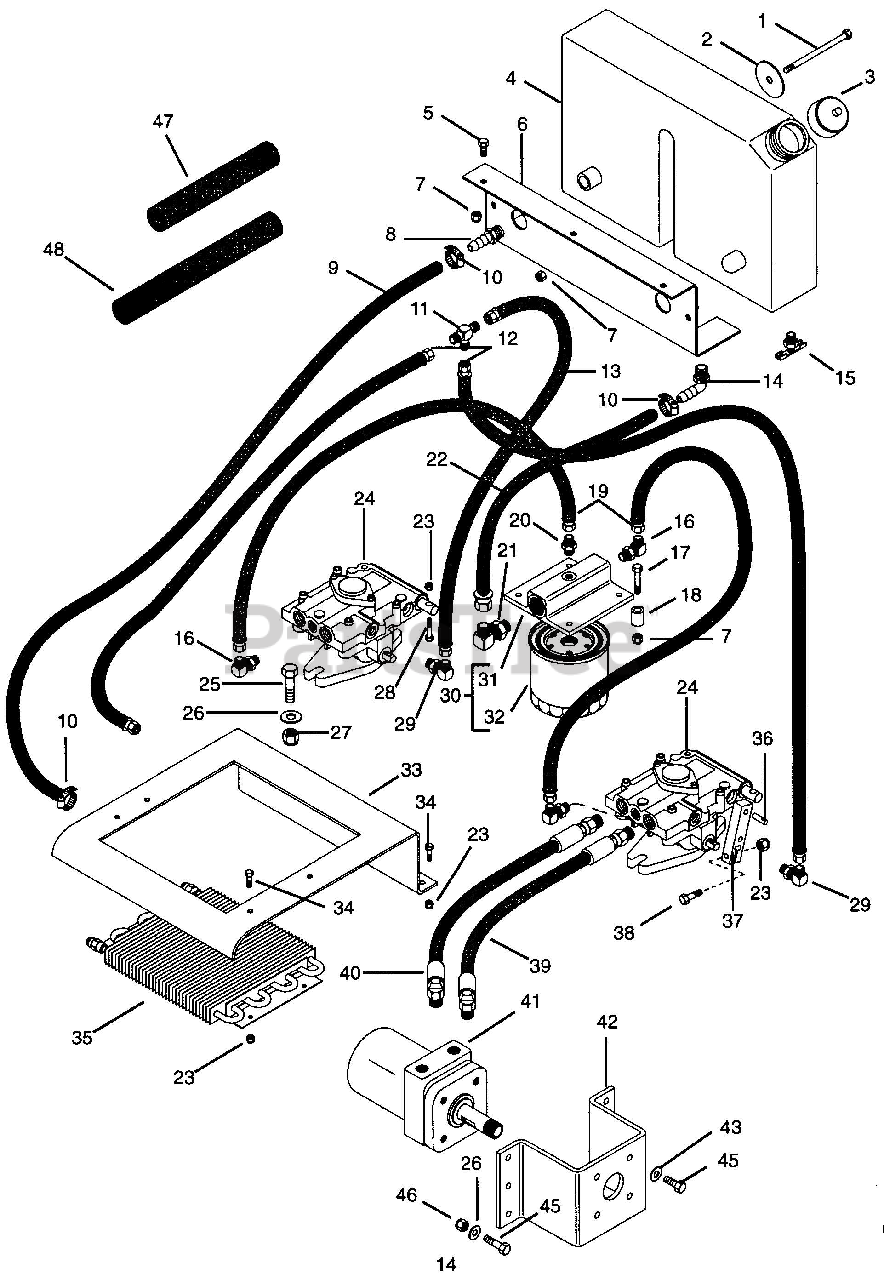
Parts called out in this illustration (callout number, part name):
1	Bolt-Hex .31-18 x 3.50
2	Washer-Flat .344 x 3.0 x .060
3	Cap - Tank
4	Tank - Hydraulic
5	Bolt-Hex .31-18 x .75 Grade 5
6	Bracket - Hydraulic Tank Mounting
7	Nut-Locking-Center .312-18 Grade 2
8	Adapter - Male
9	Hose - Oil Cooler To Tank
10	Clamp .88 Diameter Hose
11	Adapter-Tee, .56-18
12	Hose - Hydraulic Valve to Tank
13	Hose-Pump to Tee
14	Fitting-Elbow, .50 x .50
15	Cock-Drain .38 x .69 x 1.25
16	Adapter 2503-4-4
17	Bolt-Hex .31-18 x 2.00 Grade 5
18	Bushing-Split .328 x .462 x .75
19	Hose-Oil Filter to Pump
20	Adapter 0503-4-4
21	Adapter-Pipe .75-16
22	Hose-Tank to Oil Filter
23	Nut-Locking-Center .250-20 Grade 2
24	Variable Dispace Pump
25	Bolt-Hex .38-16 x 1.125
26	Washer-Flat-Steel .406 x .812 x .065
27	Nut-Locking-Center .375-10 Grade 2
28	Bolt-Hex .25-20 x 2.00 Grade 5
29	Adapter 2503-6-6
30	Assembly - Spin-On Lube
31	Assembly - Head
32	Element
33	Bracket - Oil Cooler
34	Bolt-Hex .25-20 x .75 Grade 5
35	Cooler - Oil
36	Pin-Dowel .312 x 1.25
37	Arm - Pump Actuating
38	Bolt-Hex .25-20 x 1.25 Grade 5
39	Assembly - Hose - Wheel Motor to Pump
40	Assembly - Hose - Wheel Motor to Pump
41	Motor - Hydraulic Wheel
42	Bracket - Wheel Motor
43	Washer-Lock .375 x .094
45	Bolt-Hex .38-16 x 1.25 Grade 5
46	Nut-Locking-Nylon .375 x .094
47	Sleeve 12"
48	Sleeve 12"
